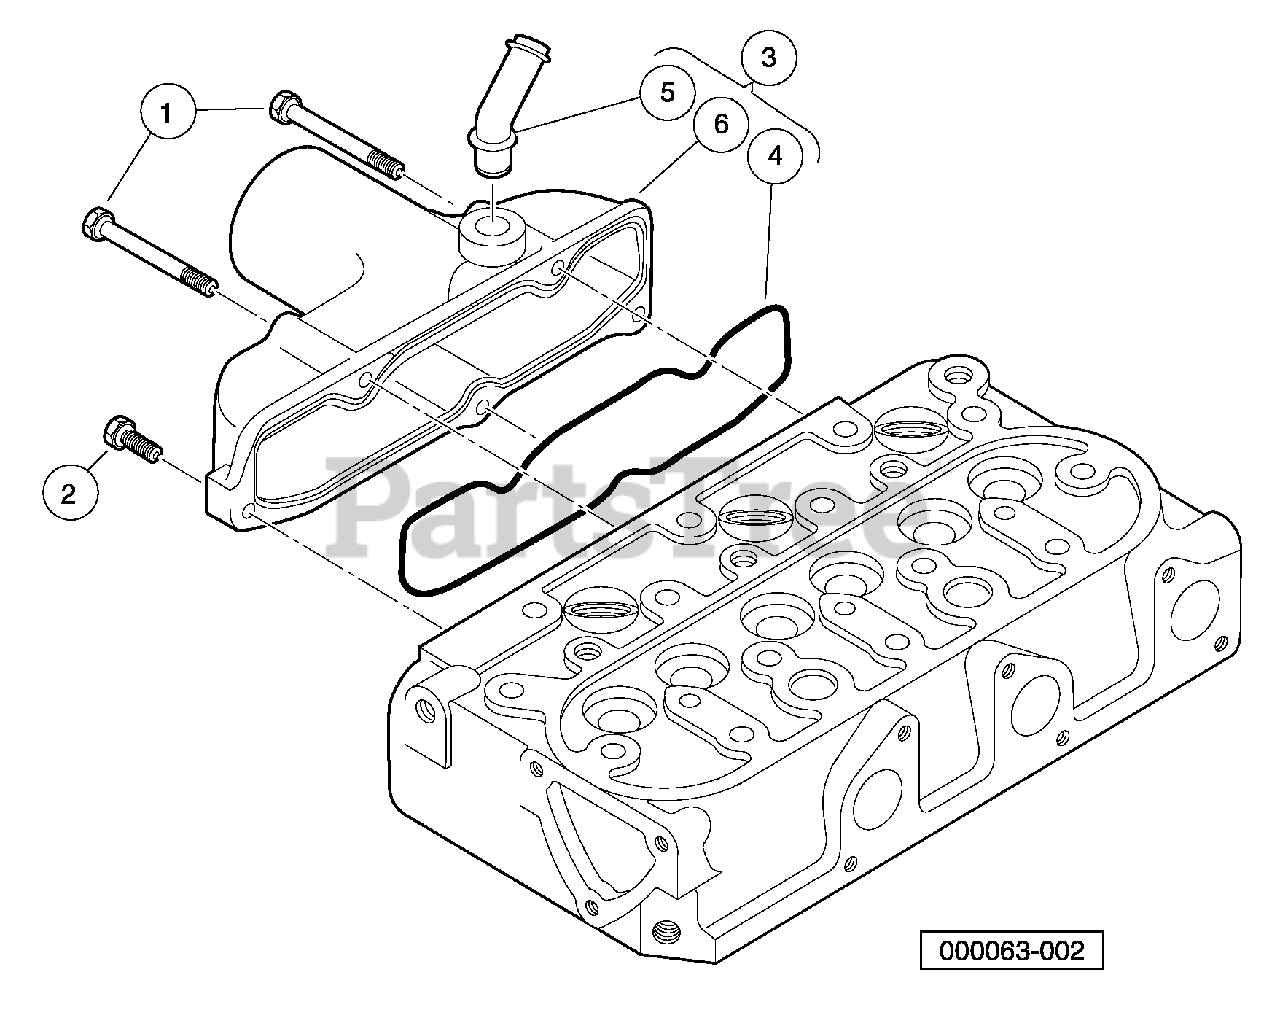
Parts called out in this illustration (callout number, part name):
1	Bolt, M6 X 1 X 45
2	Bolt, D722 Intake Manfld Lower.
3	Assembly, Intake Manifold
4	Gasket, Intake Manifold
5	Pipe, Breather
6	Manifold, Intake
